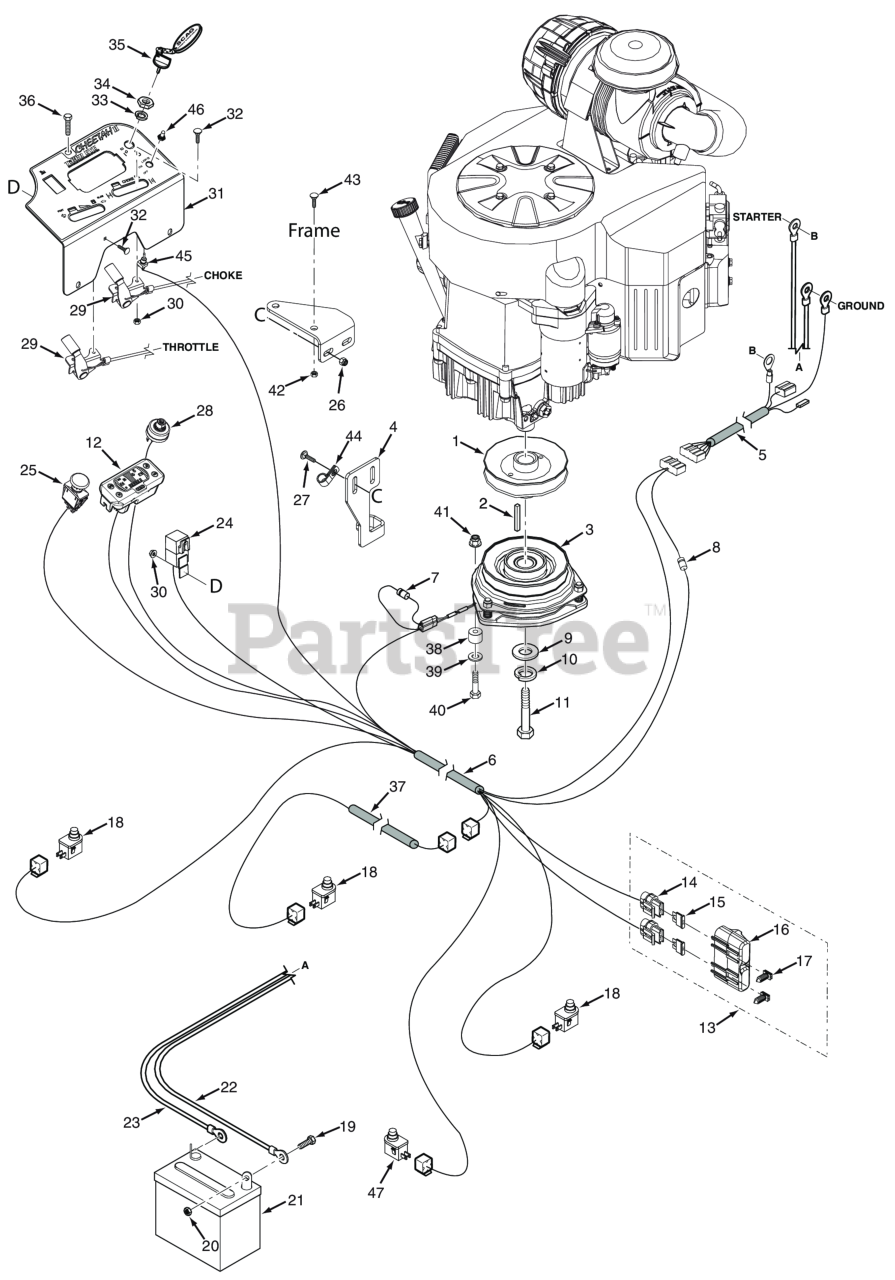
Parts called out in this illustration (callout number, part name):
1	Pulley, 5.80" Dia. - 1.125 Bore
2	Key, 1/4 x 1/4 x 3-1/4�
3	Electric Clutch w/Tag - GT-5 (ECV860, ECV940)
4	Bracket, Anti-Rotation
5	Wire Harness Adapter, Kawasaki - 22FX & 23FX
6	Wire Harness, SCZII
7	Diode, 600V 6 Amp
8	Decal, Forward Speed Selector
9	Flatwasher, 7/16-.469 x 1.75 x .25 (48, 52)
10	Lockwasher, 7/16� Spring
11	Bolt, Hex Head 7/16-20 x 2-1/4" w/Patch (Kawasaki)
12	Tiger Eye, Cluster Gauge
13	Double Fuse Assy.
14	Fuse Holder Assembly
15	FUSE, 20 AMP BLADE TYPE AUTOMOTIVE
16	Cover, Sealed Double
17	Clip, Fuse Holder
18	Switch, Interlock, Normally Open
19	Bolt, Hex Head 1/4-20 x .5" Battery, (Not Available Through Scag)
20	Nut, 1/4 - 20 Hex
21	Battery
22	Battery Cable, 27" Black (35BV & 37BV-EFI) - Briggs & Stratton
23	Battery Cable, 25" Red (Kawasaki)
24	Relay, 12V 40 AMP Standard
25	Switch, PTO - 10 Amp
26	Nut, Flange Head Elastic Stop 5/16-18
27	Bolt, Carriage 5/16-18x1" (large frame units only)
28	KEY SWITCH(INCLUDES MOUNTING HARDWARE)
29	Control Cable (Kawasaki FX921 Throttle & Choke Cable)
29	Control Cable, Throttle (35BV)
30	Nut, Elastic Stop #10-24
31	Instrument Panel w/Decal
32	Bolt, Carriage #10-24 x 1/2"
33	LOCK WASHER, 5/8" INTERNAL TOOTH
34	Nut, 5/8-32 Special
35	Key, Assembly w/Fob
36	CAP SCREW, 1/4-20 X 1/2" SERRATED FLANGE HEX
37	Wire Harness, Operator Platform -SCZ
38	Bushing, UHMW
39	Flatwasher, 5/16-.375 x .875 x .083 (35BV & 37BV-EFI)
40	Bolt, Hex Head 5/16-18 x 1-1/2" (Right Front Engine Mounting, Briggs and Kohler Only)
41	HEX NUT, ELASTIC STOP LOCK, 5/16-18
42	NUT, 3/8-16 SERRATED FLANGE HEX HEAD
43	Carriage Bolt, 3/8-16 x 1.0"
44	Clamp, Cable 1/2" I.D.
45	SWITCH, ON / OFF
46	BOOT, SWITCH
47	Switch, N/C
